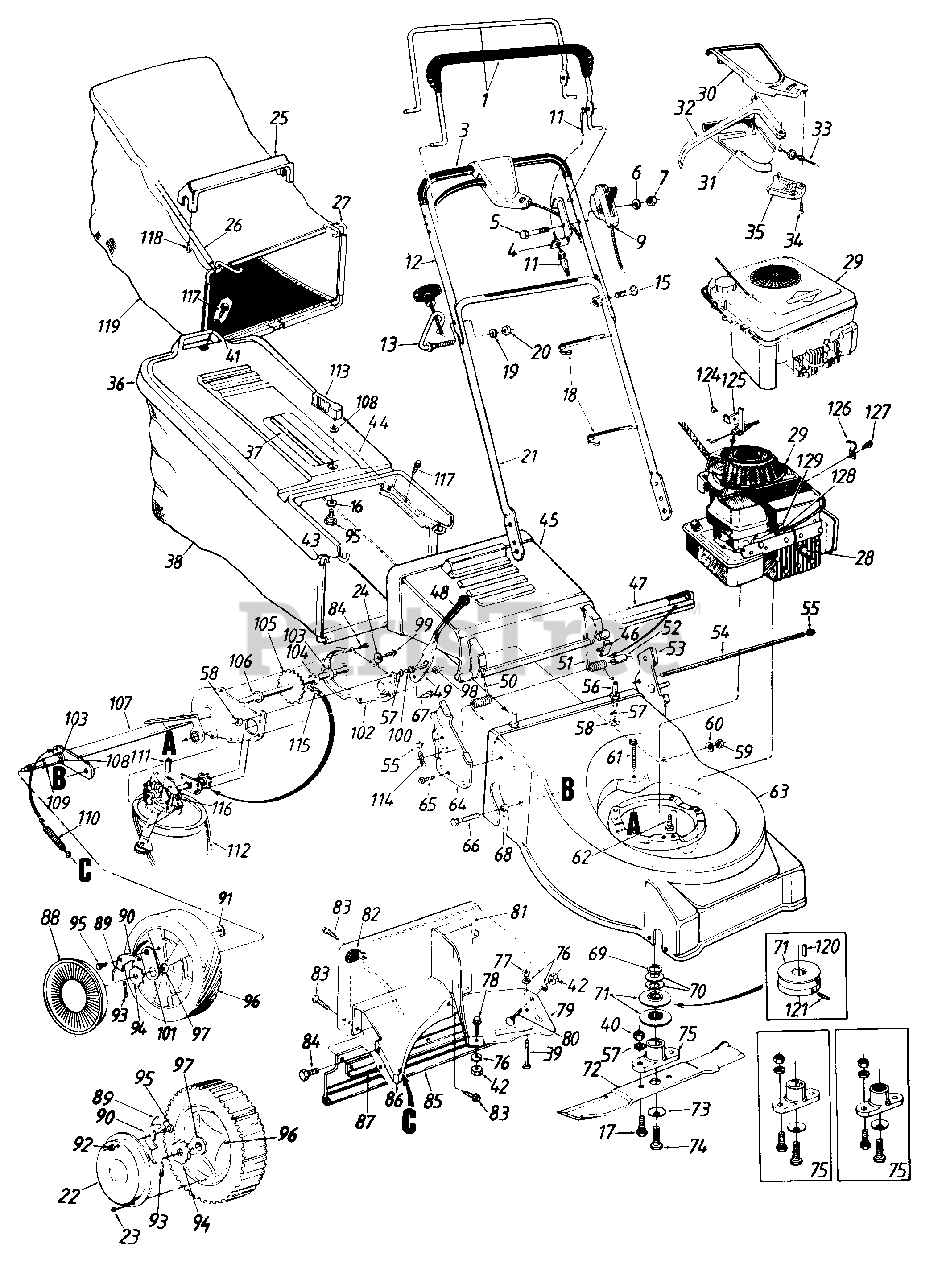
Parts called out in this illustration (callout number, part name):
1	Standard Control Handle
3	Foam Grip
4	Cable Bracket
5	Hex Bolt 1/4-20 x 1.75" Lg.
6	Spr. Wash. 1/4" I.D.
7	Hex Nut 1/4-20 Thd.
9	Throttle Control Ass'y. Comp.- 56.62"
11	Control Cable-43"
13	Rope Guide Bolt
15	Curved Carriage Bolt 5/16-18 x 1.38" Lg.
16	Bowed Washer
17	Hex Bolt 3/8-24 x 1" Lg.
18	Cable Tie
19	L-Wash. 5/16" I.D.
20	Hex Nut 5/16-18 Thd.
21	Lower Handle
22	Hub Cap
23	Pan HD. Tap Scr. #12 x .50" Lg.
24	Bell-Wash. .265" I.D. x .75"
25	Bag Handle
27	Front Catcher Frame
28	Spark Plug Boot
29	Engine
30	Control Cover Half-Upper
31	Control Cover Half-Lower
32	Control Lever
33	Drive Cable-51" Lg.
34	Flat C-Sunk Hd. Tap Scr. #10 x .75" Lg.
35	Cable Mtg. Cap
36	Hardtop Bag Cover
37	Hardtop Handle
38	Grass Bag
39	Truss Mach. Scr. 1/4-20 x 1.0" Lg.
40	Hex Nut 3/8-24 Thd.
41	Fl-Wash. .281" I.D. x .62"
42	Hex Nut 1/4-20 Thd.*
43	Front Catcher Frame
44	Rear Catcher Frame
45	Chute Deflector
46	Deflector Plug
47	Seal-Extrusion
49	Spring Lever
50	Torsion Spring-R.H.
51	Torsion Spring-L.H.
52	Spacer.255" I.D.
53	Handle Brkt. Ass'y.-L.H.
54	Hinge Pin 17.75" Lg.
55	Cap Speed Nut
56	Shld. Pin 3/8-24 x 1.43" Lg.
57	L-Wash. 3/8" I.D.*
58	Hex Jam Nut 3/8-24 Thd.
59	Hex L-Nut 3/8-24 Thd.
60	Bell-Wash. .38" I.D. x .88"
61	Hex Wash. Hd. Tap Scr. 1/4-20 x 1.5" Lg.
62	Hex L-Wash. Hd. Scr. 3/8-16x 1" Lg.
63	21" Deck Ass'y.
64	Handle Brkt. Ass'y.-R.H.
65	Hex L-Wash. Hd. AB-Tap Scr. 1/4 x .62" Lg.
66	Hex Wash. Hd. Tap Scr. 3/8-16 x .75" Lg.
67	Hex Wash. Hd. Tap Scr. 1/4-20 x .5" Lg.
68	Spacer.383" I.D.
69	Crankshaft Spacer
70	Bell-Wash. 1.01" I.D.
71	Splined Pulley Half
72	21" Blade
73	Bell-Wash. .39" I.D.
74	Hex Bolt 3/8-24 x 1.5" Lg.
75	Blade Adapter Kit (Keyed)
76	L-Wash. 1/4" I.D.*
77	Hex Jam Nut 1/4-20 Thd.
78	Hex Bolt 1/4-20 x .85" Lg.
79	Rear Belt Baffle
80	Carr. Bolt 1/4-20 x .50" Lg.*
83	Torx Mach. AB-Tap Scr. 1/4 x .62" Lg.
84	Hex B-Tap Scr. 1/4 x .38" Lg.
85	Rear Flap
89	Plastic Spring
90	Paw l.345" I.D.
91	Weld Nut 1/4-20 Thd.
92	Hex Ins. L-Nut 1/4-20 Thd.
93	Cotter Pin 1/8" Dia.
94	Ratchet Wheel 1.62" O.D.
95	Shld. Bolt .342" Dia. x .268"
96	Wheel Ass'y. Comp.-Rear
97	Bearing 1/2" I.D.
98	Shld. Spacer .50" Dia.
99	Hex Bolt1/4-20 x .62" Lg. (Gr 5)
100	Shld. Pin 3/8-24 x 1.43" Lg.
101	Pawl Plate
104	Fl-Wash. .531" I.D. x .93"
105	Rear Axle Ass'y.
106	Hex Flange Bearing
109	Spacer. 513" I.D.
110	Extension Spring 3.8" Lg.
111	Spacer.325" I.D.
112	V-Belt
113	Grass Catcher Locking Knob
114	Internal Cotter Pin 5/16" Dia.
115	#48 Chain .50" Pitch x 30 Links
116	Transmission Comp.
117	Hex L-Wash. H.D. AB-Tap Scr. 1/4 x .62" Lg.
118	Hex AB-Tap Scr. #12 x 1.25" Lg.
119	Grass Bag
120	Sq-Key 3/16" x 3/4" Lg.
121	Set Scr. #10-32 x .25" Lg.
124	Pop Rivet .156" Dia.
125	Cable Brkt.
126	Cable Clamp
127	Hex B-Tap Scr. #10 x .38" Lg.
128	Hex B-Tap Scr. #10 x .5" Lg.
129	Cable Clamp
